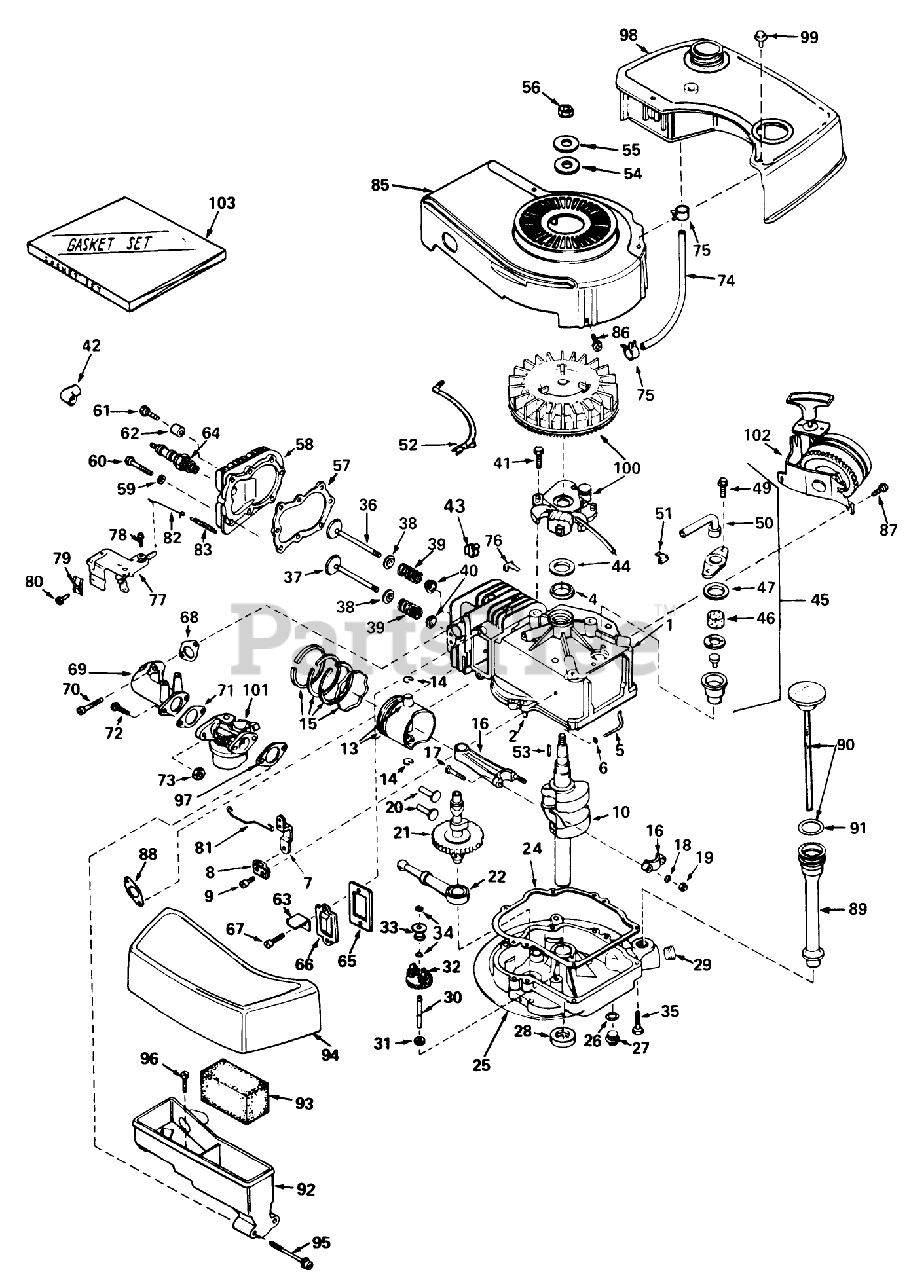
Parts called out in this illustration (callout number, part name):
1	Cylinder Assy. (Incl. Ref. #2, 4 105)
2	Pin-Dowel
4	OIL SEAL
5	Rod, Governor (Incl. No. 36)
6	Washer-Flat
7	Governor Lever
8	Clamp-Lever, Governor
9	Screw
10	Crankshaft
13	Piston Pin Assembly (Incl. 2 of No. 14) (.010 Oversize)
13	Piston Pin Assembly (Incl. 2 of No. 14) (.020 Oversize)
14	Ring-Retaining, Piston Pin
15	Ring Set Piston (Std.)
15	Ring Set Piston (.010 Oversize)
15	Ring Set Piston (.020 Oversize)
16	Rod Assy., Connecting (Incl. Ref. #17)
17	Bolt, Connecting
18	Washer
19	LOCKNUT
20	Lifter-Valve
21	Camshaft(Mech.Comp. Release)
22	Oil Pump ASM
24	Gasket, Mounting
25	Filter, Air Cleaner
26	Gasket-Oil Drain
27	Plug Oil Drain
28	Seal Oil
29	Plug Oil Drain
30	Shaft-Governor
31	Washer-Flat
32	Governor Gear ASM
33	Spool-Governor
34	Ring-Retaining
35	Screw (1/4-20 x 1-1/4)
36	Valve, Intake (Incl. Ref. #38, 39 40) (Std.)
36	Valve, Exhaust (1/32" Oversize) (Incl. Nos. 8, 9 10)
37	Valve, Exhaust (Standard) (Incl. Nos. 8, 9 10)
37	Valve, Exhaust (1/32" Oversize) (Incl. Nos. 8, 9 10)
38	Cap-Upper Valve Spring
39	Spring-Valve
40	Cap-Valve, Spring
41	Screw
42	Cover-Spark Plug
43	51004 GIL ROTARY TI
44	Gasket Stator
45	Breather Assy. (Incl. Ref. #46, 47, 49, 50 51 )
46	Element-Breather
47	Gasket-Breather
49	Screw, Hex Hd. w/Conical
50	Tube, Breaker
51	Clip, Breather
52	Wire Ground
53	Key-Flywheel
54	Washer Flat
55	Washer-Spring
56	Hex Nut
57	63573 GIL 42 SNWTHW
58	Head Cylinder
59	Washer
60	Screw
61	Screw Hex Hd. Cap
62	Space
63	Retainer Clip
64	Plug, Spark (Champion RCJ-8)
65	Gasket-Breather
66	Cover-Valve
67	Screw
68	Gasket, Intake
69	Pipe, Intake
70	Screw (1/4-20 x 1)
71	Gasket-Carburetor
73	Nut and Lock Washer (1/4-28)
74	Line-Fuel
75	Clamp-Line, Fuel
76	Clip-Wire
77	Control Assy., Speed (Incl. Nos, 76, 78 89)
78	Screw (10-24 x 3/4)
79	Conduit
80	Screw (10-32 x 3/8)
81	Link Governor
82	Link Governor Spring
83	Spring Governor
85	Housing, Blower
86	Screw
87	Screw (1/4-20 x 1/2)
88	Gasket Exhaust
89	Tube Fill
90	Dipstick, Oil (Incl. Ref. #101)(Twist Lock)
91	O-Ring
92	Body Air Cleaner
93	Filer, Air
94	Cove, Air Cleaner
95	Screw Fil Hd.
96	Screw, Hex Hd.
97	Gasket-Air Cleaner
98	Tank Fuel
99	Screw (10-32 x 35/64)
100	Magneto
101	Carburetor (Incl. No. 71)
102	Starter, Side Mount
103	53024/VAR.16HP O/P
